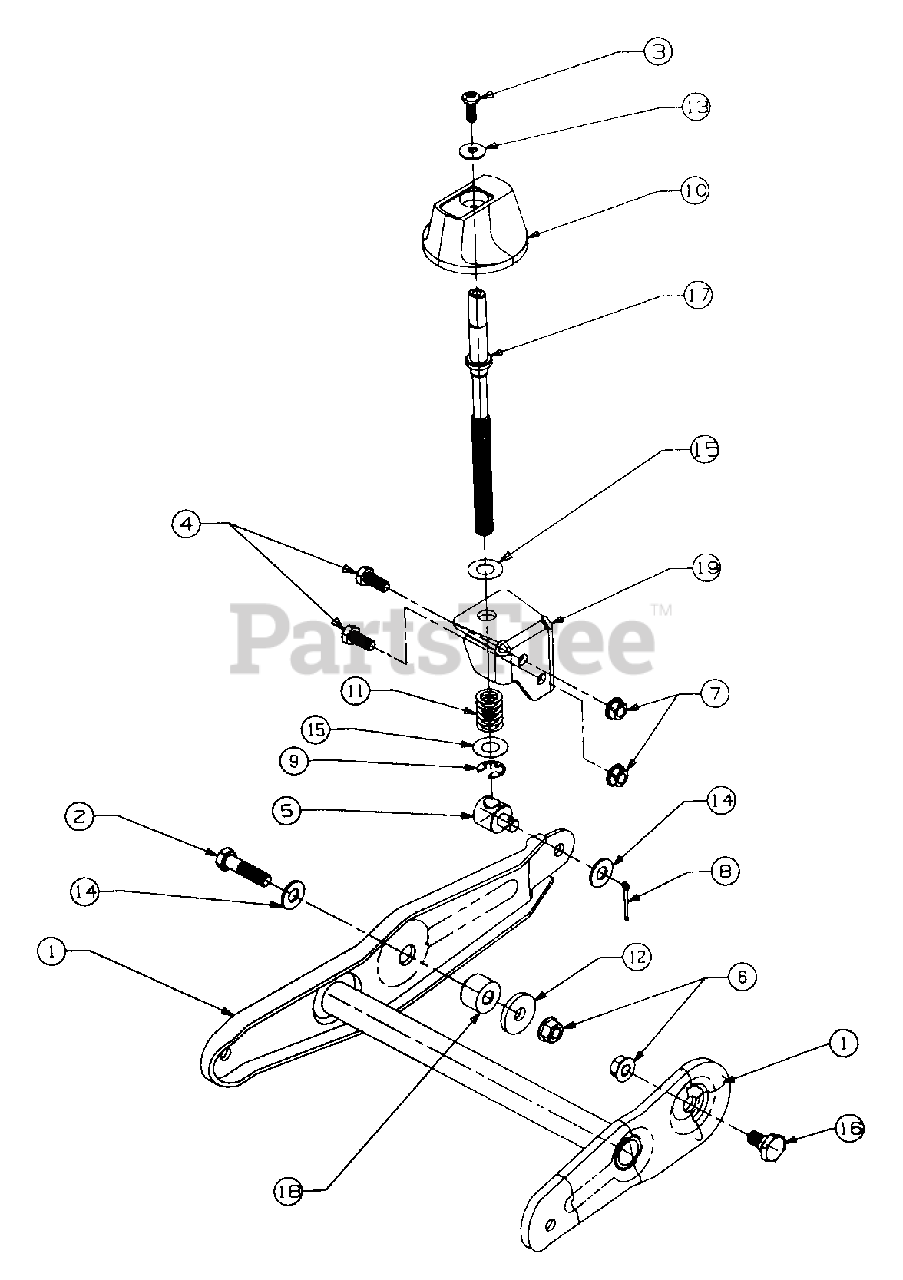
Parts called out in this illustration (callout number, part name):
3	SCREW-MACHINE PAN HD
4	SCREW-HEX
5	FERRULE - ADJUSTABLE
6	NUT-HEX FLANGE LOCK
7	NUT-HEX FLANGE
8	PIN-COTTER
9	RING-E
10	KNOB-PLASTIC
11	SPRING-COMPRESSION
12	WASHER- FLAT
13	WASHER-BELL
14	WASHER-FLAT
15	WASHER-FLAT
16	SCREW-SHOULDER
17	ROD-ADJUSTABLE
